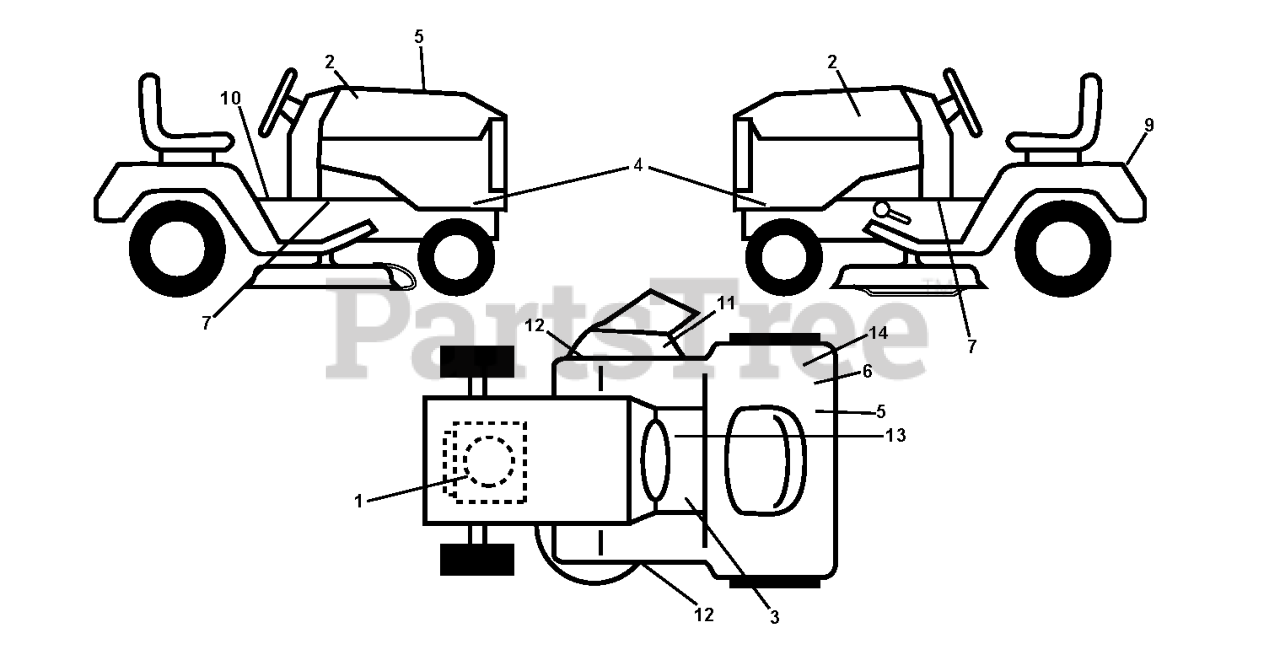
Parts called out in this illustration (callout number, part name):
1	DECAL
2	RP.DECAL.BADGE.170MM.TEXTLOGO
3	DECAL
4	DECAL.SDPNL.LTH19530.
6	DECAL
9	DECAL BTRY SYMBOLS
10	LABEL
11	DECAL.WARN.DFLECT/CTFINGR.SRD
12	Decal, Mower V-Belt Schematic
13	DECAL PARK BRAKE
14	DECAL 80 DBA
